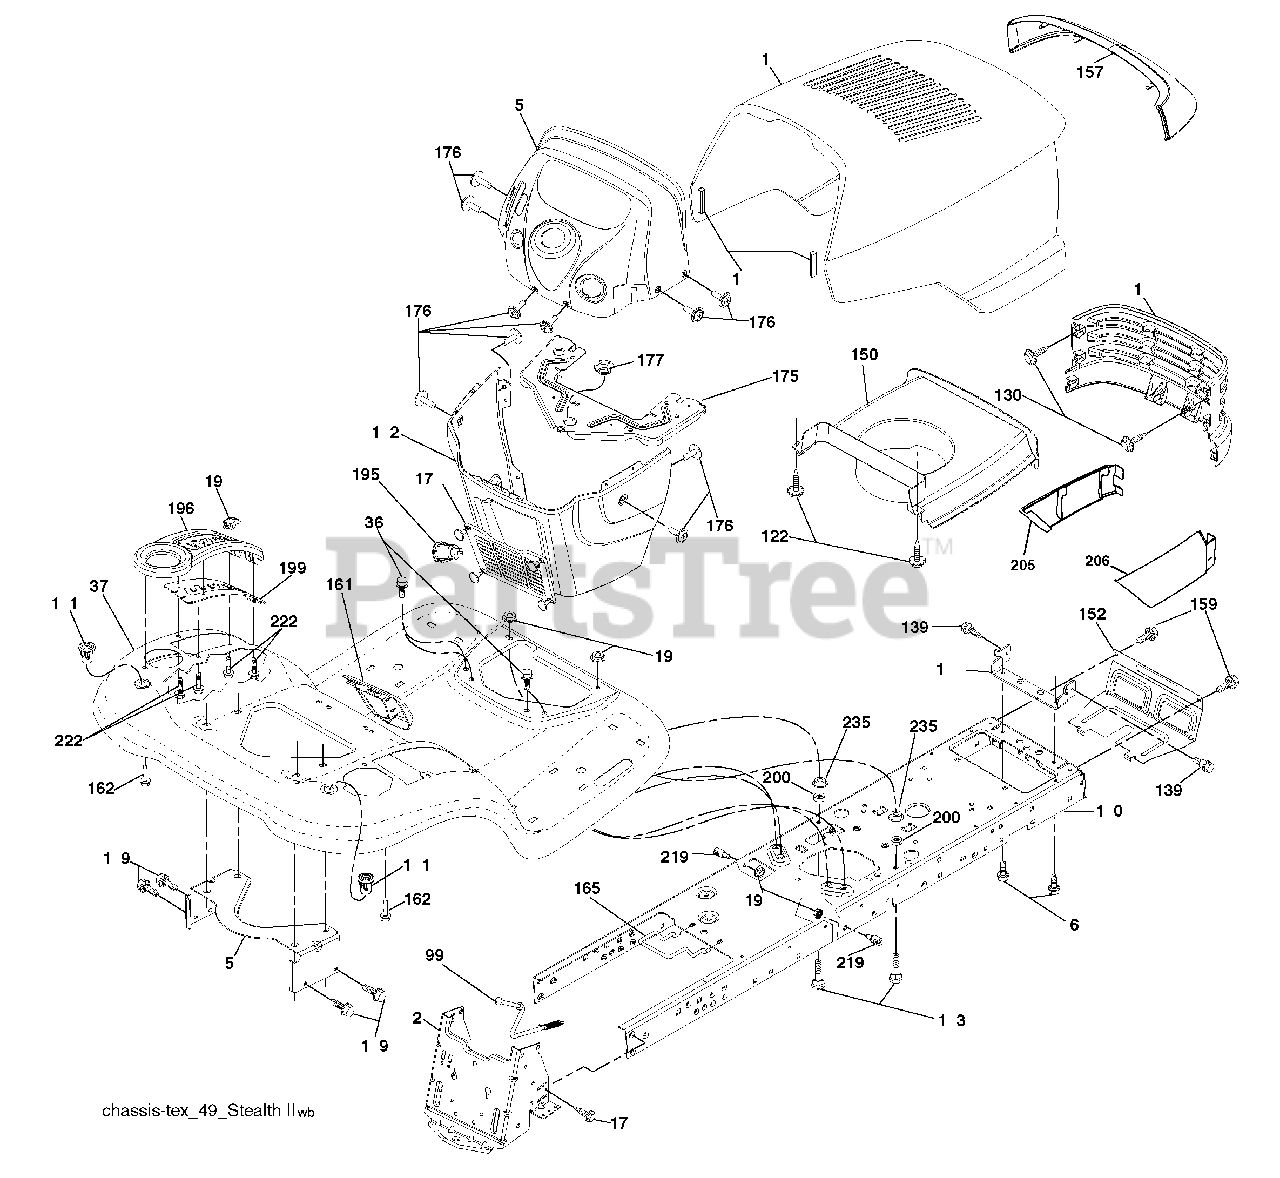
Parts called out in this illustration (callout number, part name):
2	Drawbar
5	Dash
14	Hood
17	Screw 3/8-16 x .75
18	Grille
36	Screw 5/16 - 18 x 3/4
37	Fender
58	Bracket Fender
68	Screw Thdrol 5/16-18 x 1/2
99	Rod Bypass Asm.
122	Screw WSHD Hex 10-32 x 5/8
130	Screw 10 x 3/4 Single Lead-Hex
139	Bolt Shoulder
148	Bumper
150	Duct Heat Hood
152	Shield Browning/Debris
157	Lens Bar
159	Screw Hexwsh Thdrol 3/8-16 x 3/4
161	Console Fuel Window
162	Screw Hex Wsh Hi-Lo 1/4 x 1/2
165	Bracket Support Tank
175	Crossmember
176	Screw #10-24 x 5/8 Rnd Qudrx
177	Bushing Steering
178	Cargo Asm. Net
181	Bushing Mtg. Fender Crgo.
182	Dash Lower
183	Bolt Fin Hex 5/16-18UNC x 1-1/4
188	Bracket Pickoff Hood
189	Screw 5/16-18 x 3/4
194	Nut Lock Hex Flange 5/16-18
195	Outlet 12-Volt
196	Console Asm. Deck Lift
198	Indicator Deck Lift
199	Plate Deck Lift
200	Nut Center Lock 5/16 - 18 UNC
205	Skirt Hood RH
206	Skirt Hood LH
219	Stud Fastener
222	Screw thd Roll 1/4-20 x 5/8
235	Spacer Fender
